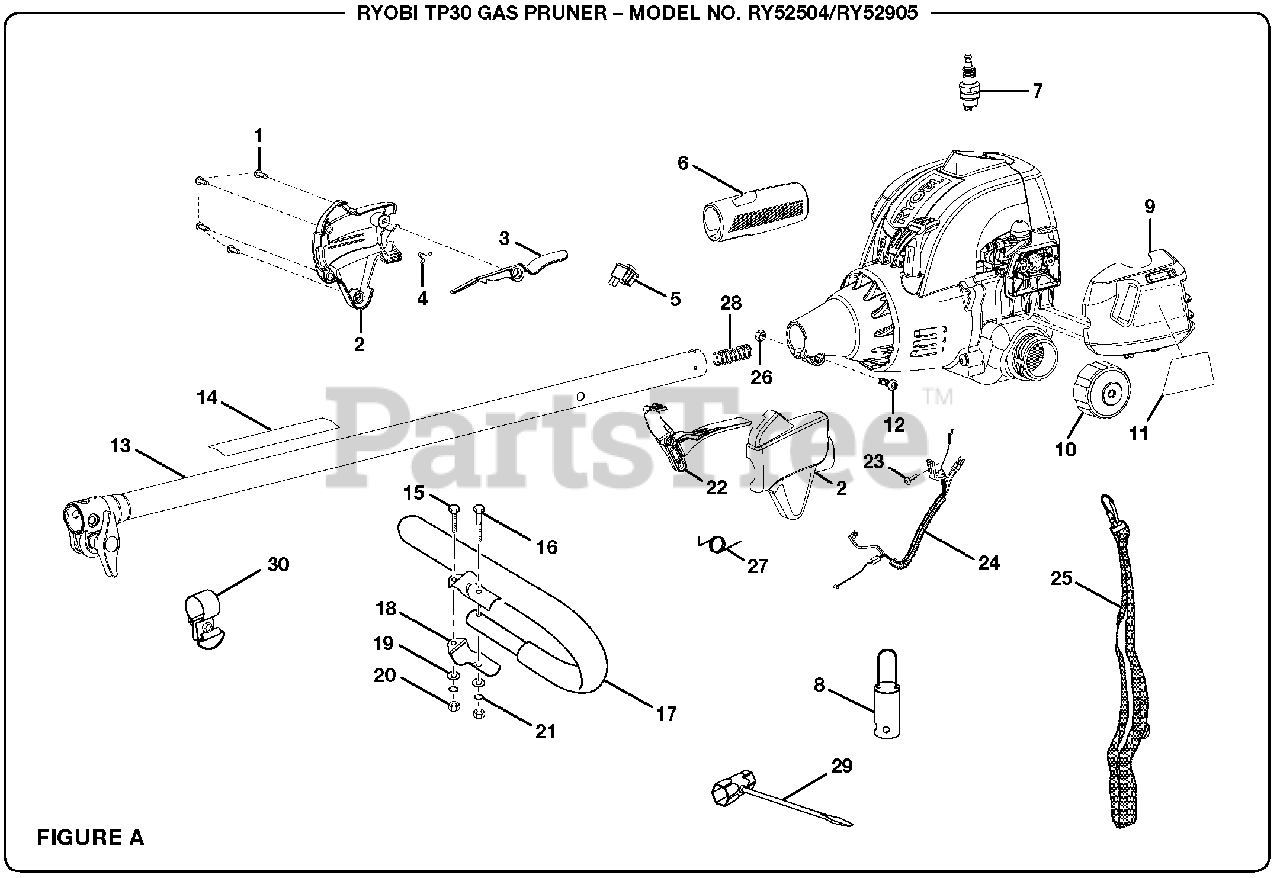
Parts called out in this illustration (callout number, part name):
1	Screw (M4 x 20 mm)
2	Control Handle Assembly
3	Trigger Lock
4	Strap Hanger
5	Switch (Momentary Contact)
6	Rear Handle
7	Spark Plug (Champion RCJ6Y)
8	Hanger Cap
9	Air Filter Cover
10	Fuel Cap Assembly
11	Starting Label
12	Bolt (M6 x 20 mm)
13	Upper Boom Assembly
14	Warning Decal
15	Short Bolt (1/4-20 x 1 in., Hex Hd.)
16	Long Bolt (1/4-20 x 1-1/2 in., Hex Hd.)
17	"J" Handle w/Grip
18	Handle Bar Clamp
20	Hex Nut (1/4-20)
21	Lock Washer
22	Throttle Trigger
23	Screw (10-24 x 7/8 in.)
24	Throttle and Lead Assembly
25	Shoulder Harness
26	Hex Nut (M6)
28	Compression Spring
29	Combination Wrench
30	Strap Hanger Assembly
